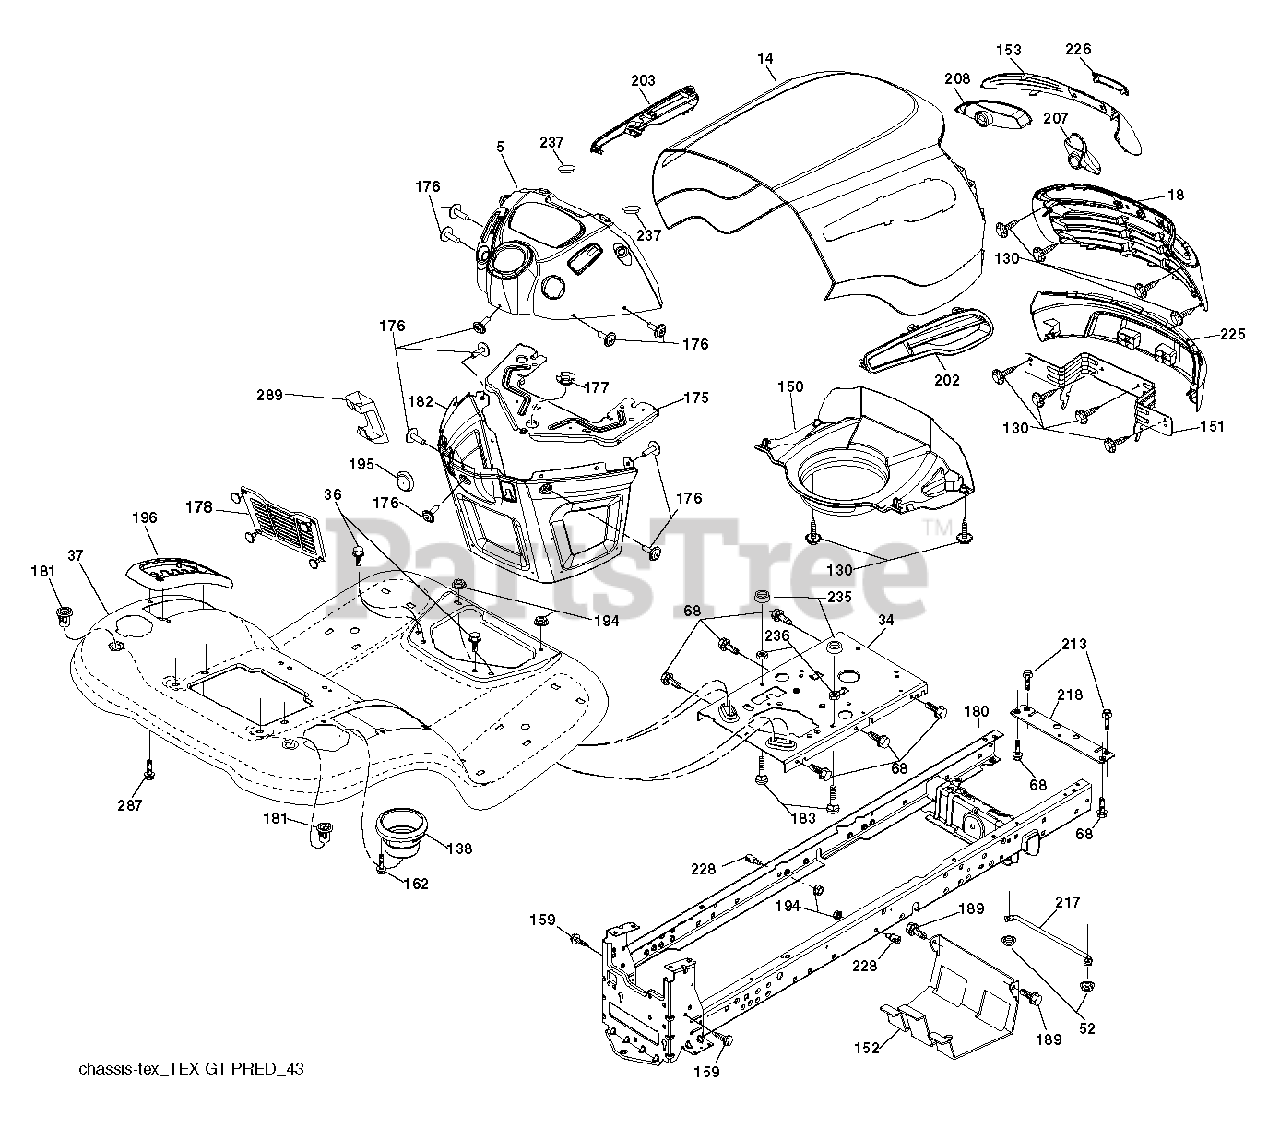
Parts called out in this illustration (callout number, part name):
34	PLATE.ENGINE.WELDED.CHASSIS
36	SCREW 5/16"
52	LOCKNUT
68	SCREW LT
130	SCREW.#10 X 0.750.BOS THREAD
138	CUPHOLDER.TL.TEX.BLACK
152	SHIELD BROWNING
159	SCREW, 3/8-16X3/4
162	SCREW.HI-LO.CONSOLE
175	PLATE.CROSSMEMBER.HUSQ
176	SCREW.#10-24X5/8.RN.QU
177	BUSHING,STEERING
178	CARGO.ASM.NET.TXGT.W/C
180	CHASSIS
181	FEND/FTRST.PCH.CPH.NFW
182	DASH.LOWER.COMMON.12V.ADAPTOR
183	BOLT.5/16-18X1-1/4 FULL THD
189	SCREW
194	NUT LOCK HEX FLANGE 5/16-18
195	PLUG.HOLE.DASH.LOWER.12V.BLK
196	CONSOLE.ASM.DECKLFT.BL/RBT.TLT
213	BOLT
217	ROD.PIVOT.HOOD
218	X-PIECE.HOOD.STOP.NON/
228	STUD.FASTNER.W/ANTI-ROTATE
235	SPACER FENDER
236	NUT.CENTERLOCK.5/16-
237	PLUG.MOUNT.CARGO.BLK
289	PLUG.N/CRUISE.COMMON.YT/GT.BLK
